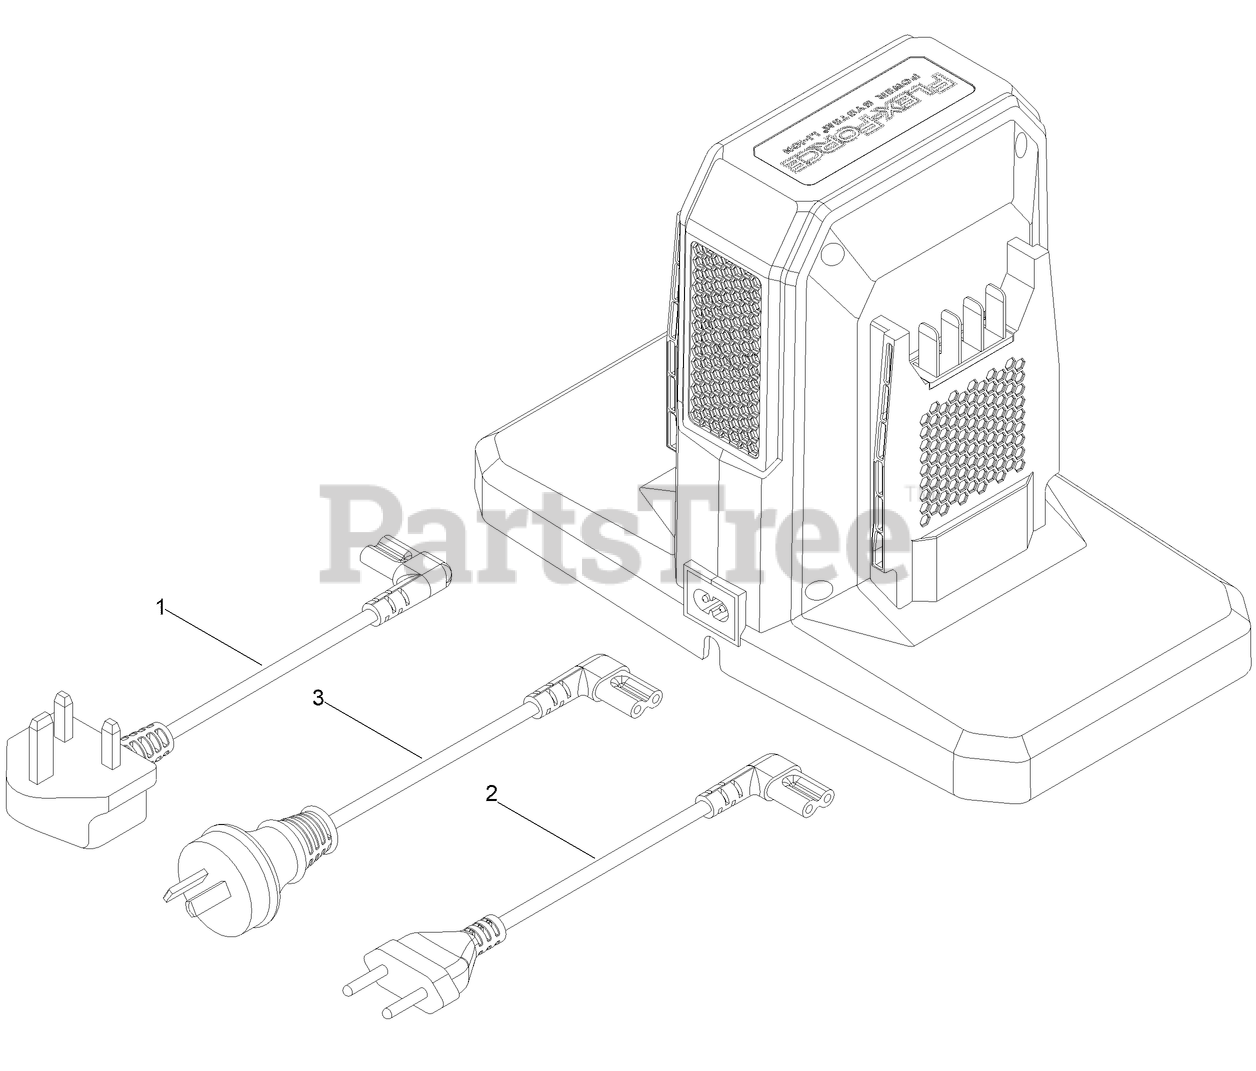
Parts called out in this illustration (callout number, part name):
1	CORD-DUAL POD CHARGER, UK
2	CORD-DUAL POD CHARGER, CE
3	CORD-DUAL POD CHARGER, AU/NZ
